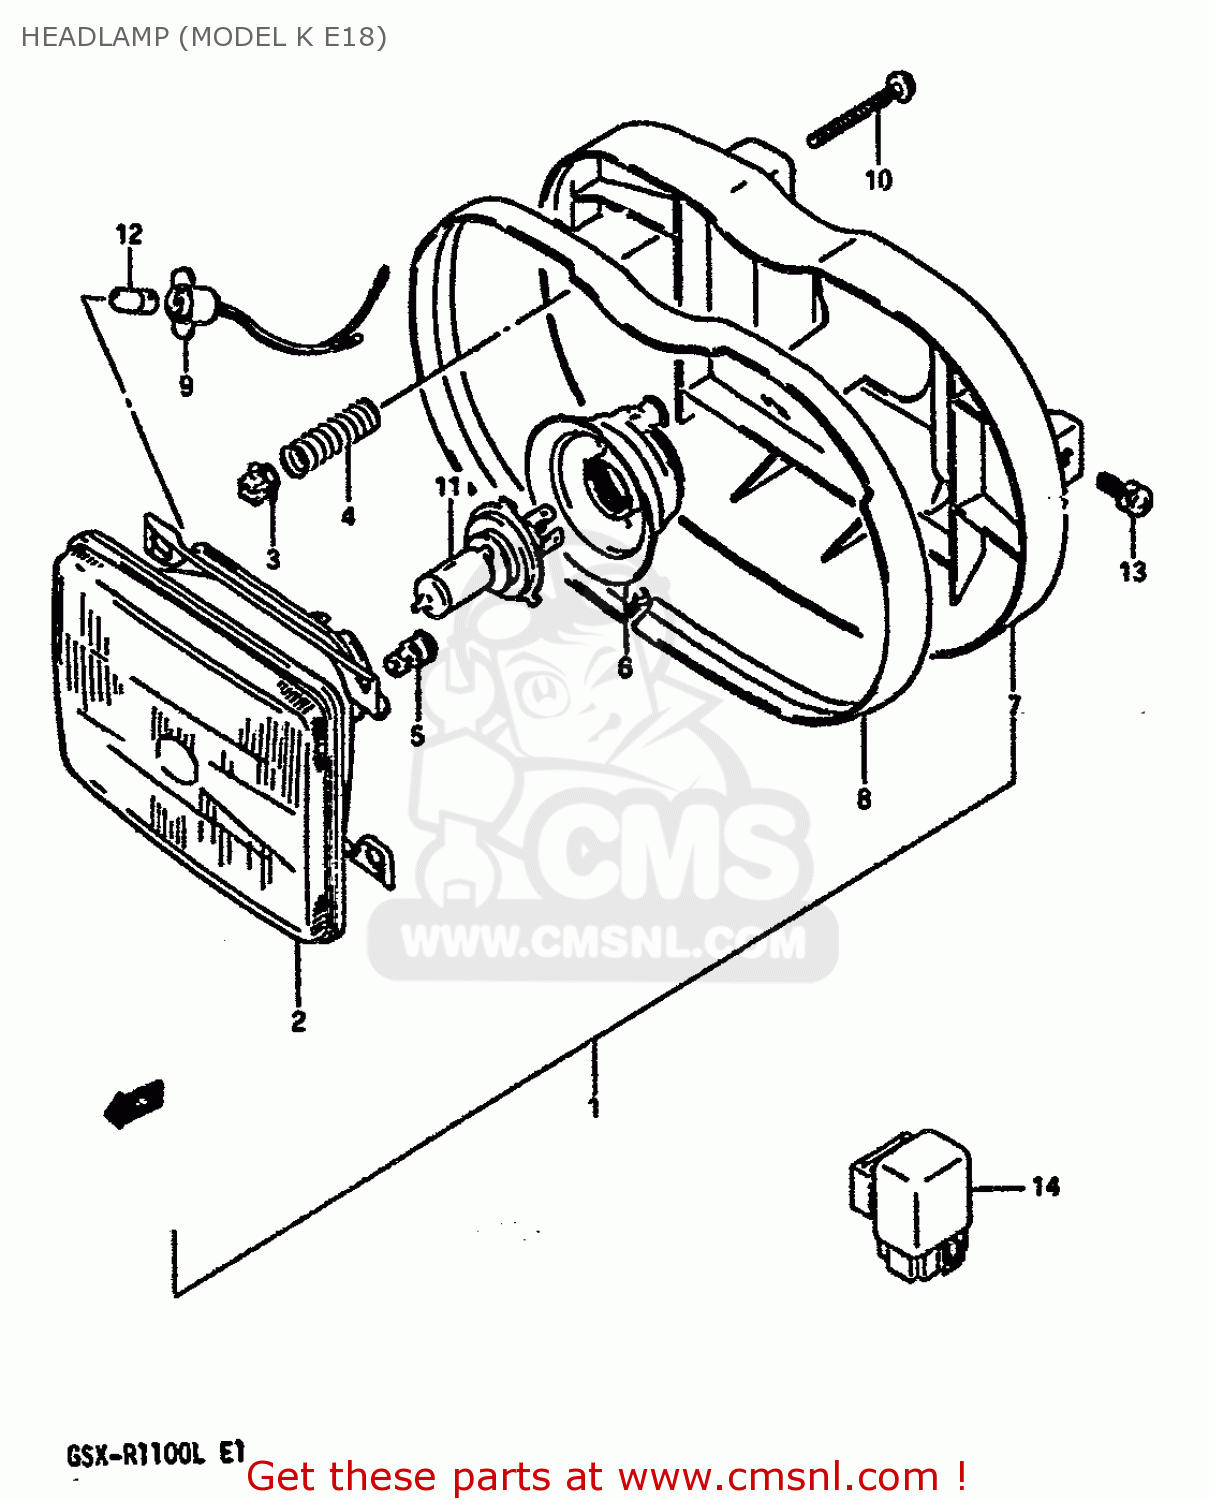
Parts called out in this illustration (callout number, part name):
1	HEADLAMP ASSY
2	LAMP UNIT
3	NUT
4	SPRING
5	SCREW,SPHERICAL
6	COVER,HEADLAMP SOCKET
7	HOUSING,HEADLAMP
8	GASKET,HEADLAMP (NAS)
9	SOCKET
10	SCREW,ADJUSTING
11	BULB(12V60/55W,H4)
12	BULB(12V4W)
13	SCREW
14	RELAY ASSY,HEADLAMP
